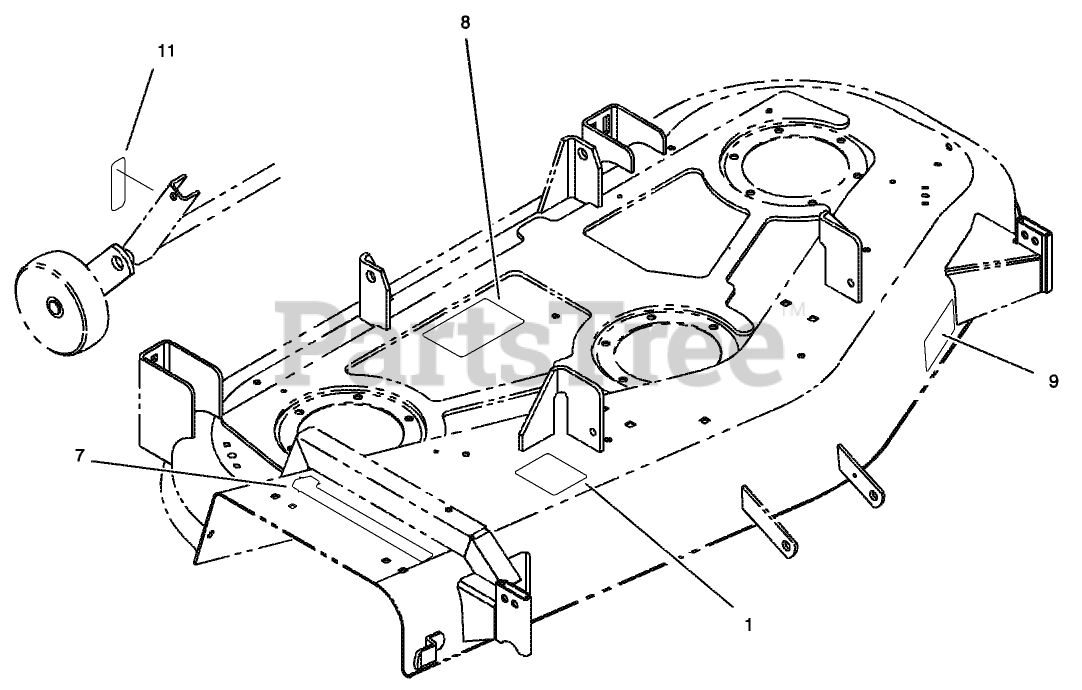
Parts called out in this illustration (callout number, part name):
1	DECAL-BELT ROUTING
7	DECAL-DECK
8	DECAL-BELT ROUTING
9	DECAL-ADJUSTMENT, WHEEL
11	DECAL-HOC
